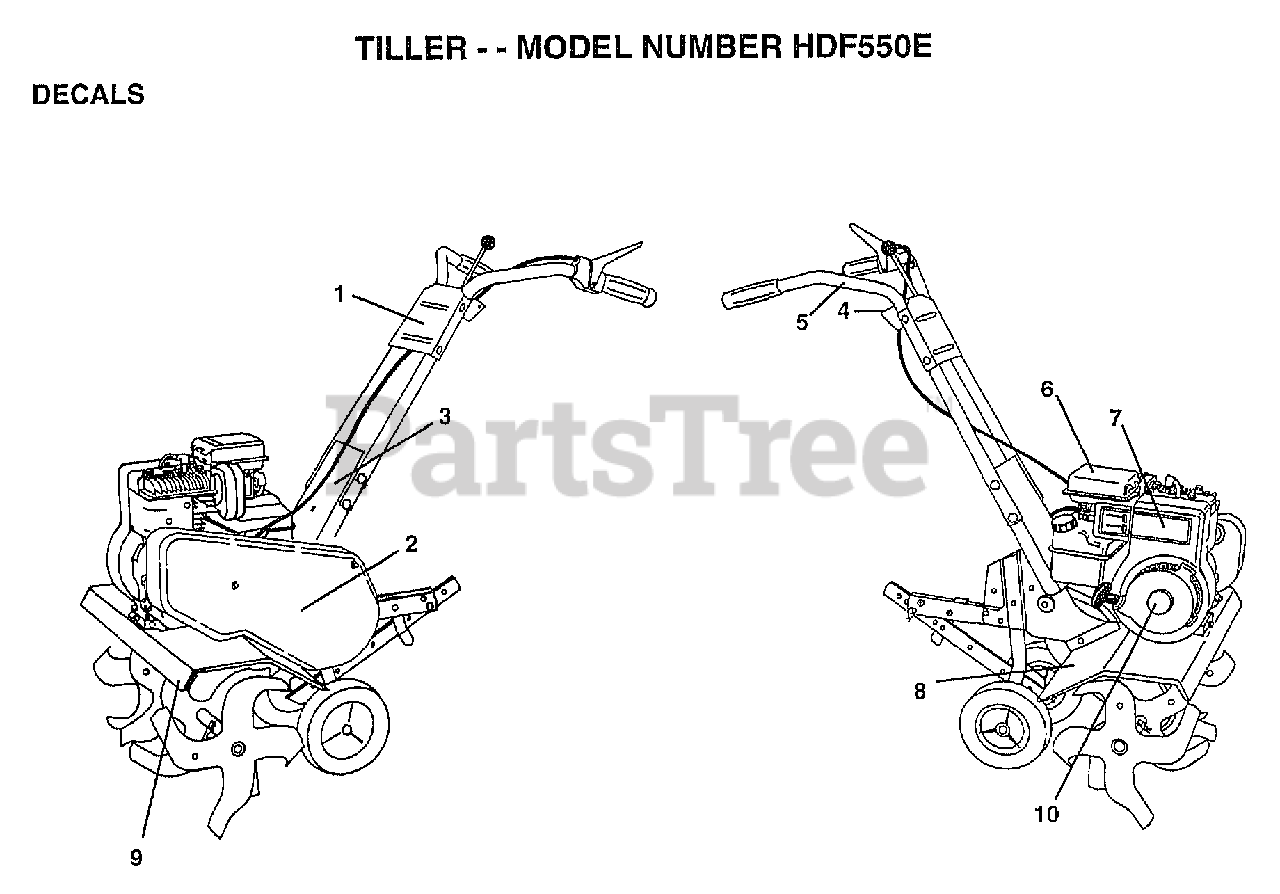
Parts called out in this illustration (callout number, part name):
1	"DECAL PANEL,CTRL"
2	"DECAL GUARD,BELT"
3	"DECAL PANEL,FORWD"
4	DECAL.PNL.CTRL.ES
5	DECAL.HAND.PLACE
6	DECAL.CAUTION.E/S
7	DECAL, BRIGGS & STRATTON
8	DECAL.WARN.ROT.TI
9	"DECAL SHIELD,TINE"
10	DECAL, 5 HP
